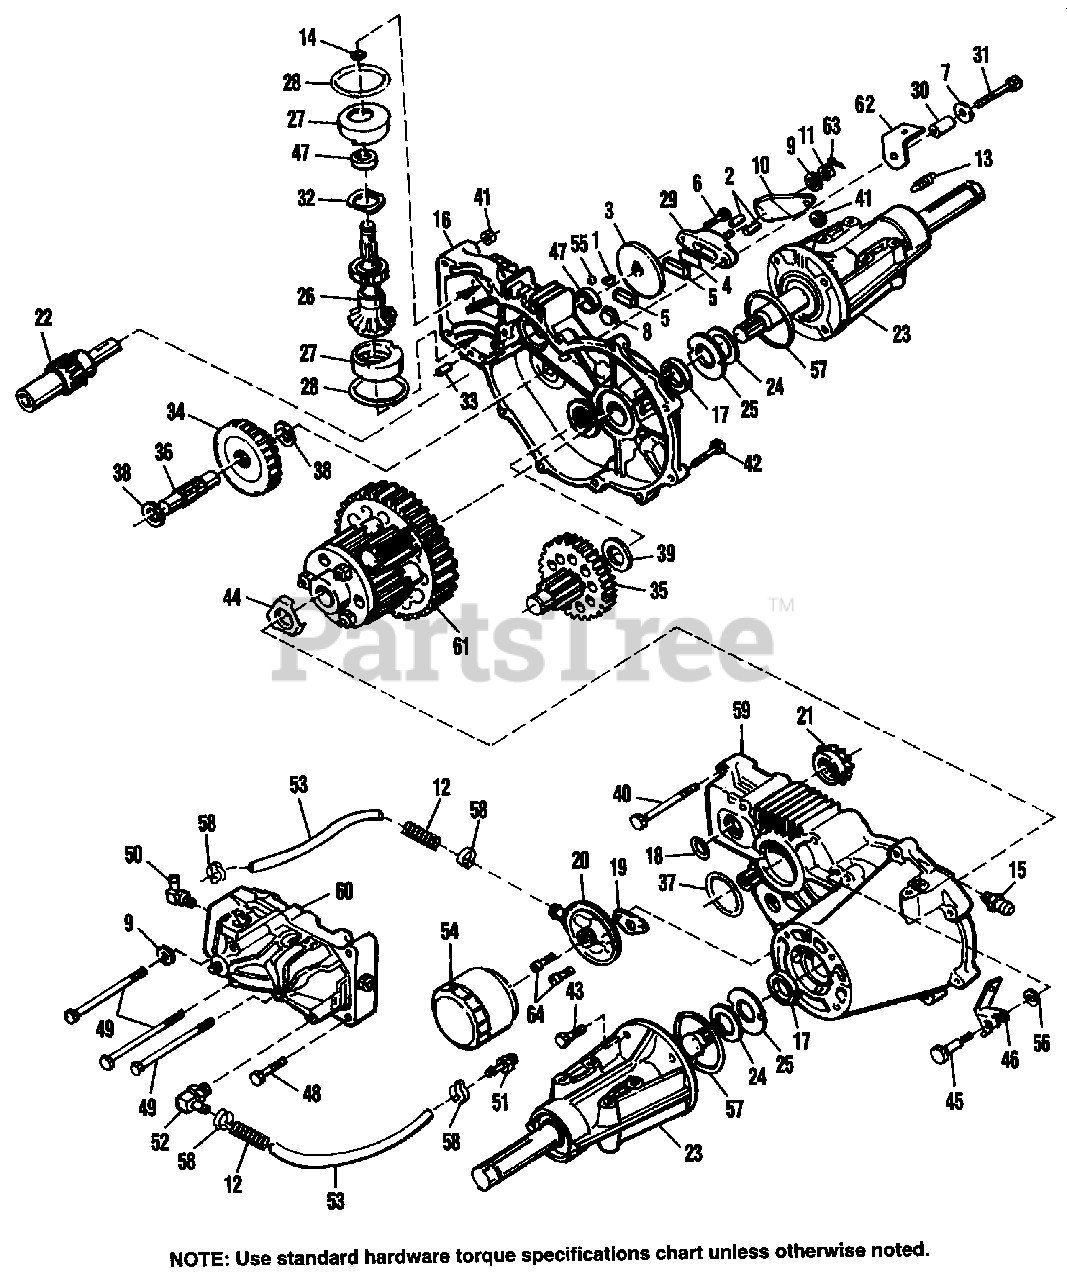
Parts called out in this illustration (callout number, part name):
1	KEY, Hi-Pro, 3/16 x 5/8
2	PIN, Brake Actuating
3	DISC, Brake
4	PLATE, PUCK
5	PUCK, Brake
6	BOLT, Nyloc, Gr. 5, 1/4-20 x 1
7	WASHER, Flat
8	PLUG, Straight Thread
9	WASHER, 7/8 x x 7/16 x
11	NUT, Castle, 7/16
13	SPRING, Extension
14	RING, Wire Retaining
15	FITTING/O-RING ASSY.
16	HOUSING ASSY., RH
17	OIL SEAL, 63/64 x 1-1/2 x 1/4
18	QUAD RING
19	GASKET, Filter Base
20	BASE, Filter Assy.
21	PINION ASSY.
22	BRAKE SHAFT ASSY.
23	AXLE MOUNTING HORN ASSY.
24	WASHER, 1 x 1-5/8 x 5/64
25	WASHER, 1 x 2-1/16 x 3/32
26	INPUT ASSY.
27	BEARING, Retainer
28	QUAD RING
29	BRAKE YOKE ASSY.
31	BOLT, 1/4-20 x 2
32	WASHER, Wave
34	GEAR, Reduction, 14T-38T
35	FINAL DRIVE PINION ASSY.
37	O-RING
38	WASHER, 5/8 I.D. x 1-5/32 O.D.
39	WASHER, 7/8 I.D. x 1-1/2 O.D.
40	BOLT, Hex Hd., 5/16-18 x 3-1/2
41	LOCKNUT, Hex, 5/16-18
42	BOLT, Hex, Gr. 5, 5/16-18 x 1/2
43	CAPSCREW, Hex, Gr. 5, 5/16-18 x 1
44	WASHER, Differential, 1/2
45	BOLT, Shoulder
46	ARM, Freewheel Actuating
47	SEAL, Oil, 5/8 x 1 x 1/4
48	BOLT, Hex, Gr. 5, 5/16-18 x 1-3/4
49	BOLT, Hex, Gr. 5, 5/16-18 x 1/2
50	FITTING, 1/2, Beaded, 90o, 9/16, SAE
51	FITTING, 1/2, Straight, 9/16, SAE
52	FITTING, 1/2, Beaded, 90o, 7/8, SAE
53	HOSE, 1/2", 8-3/4" Long
54	FILTER, Spin-on, Bypass
55	WASHER, 11/32 I.D. x 9/16 O.D.
57	O-RING
58	PINCH CLAMP
59	HOUSING ASSY., LH
61	DIFFERENTIAL ASSY.
63	COTTER PIN
64	CAPSCREW, 1/4-20 x 1
